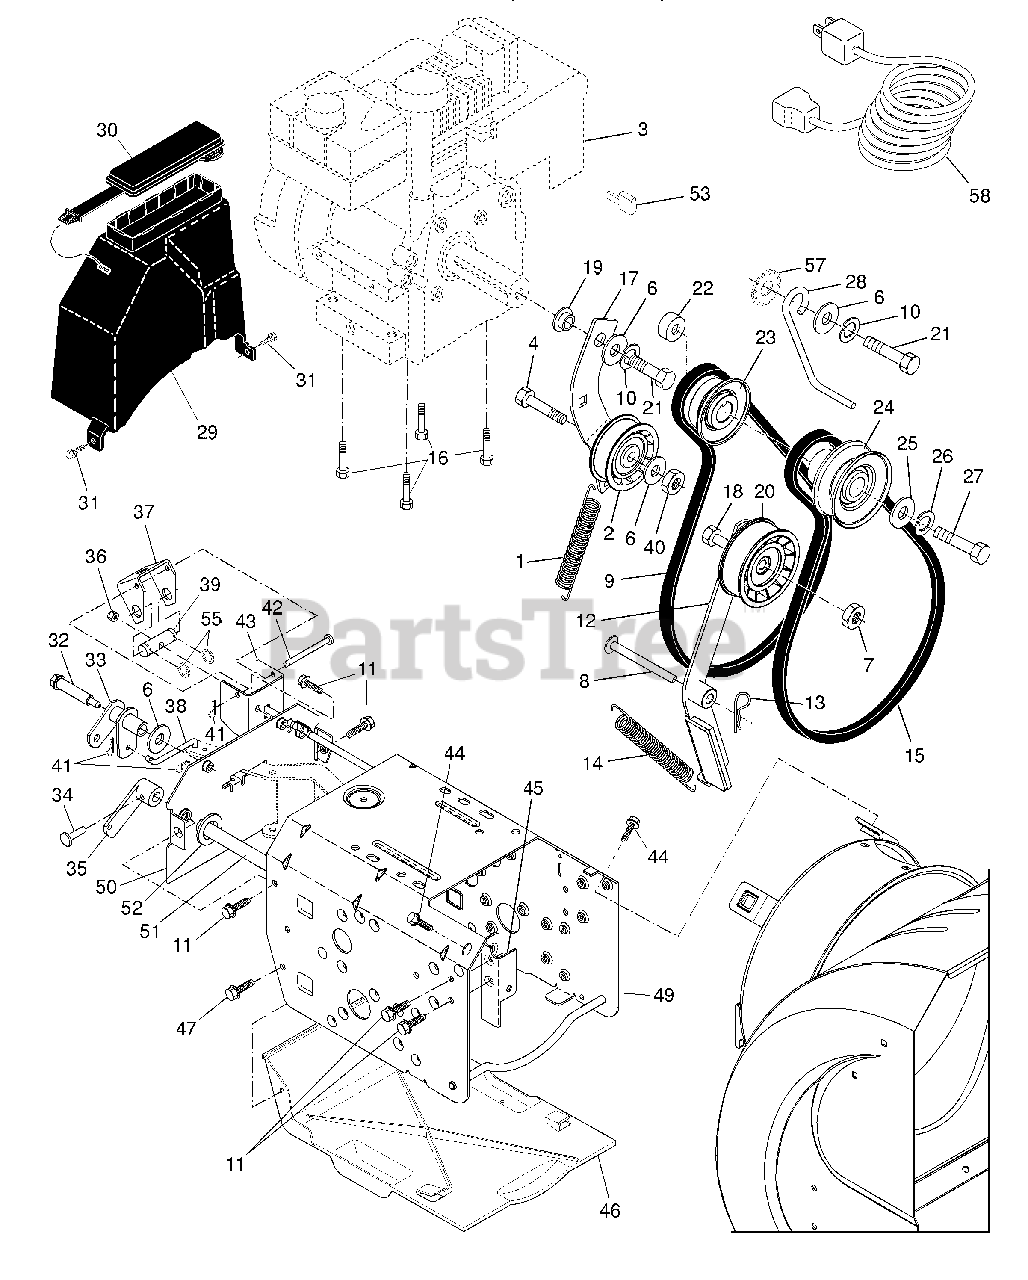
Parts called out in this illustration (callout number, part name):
1	Spring, Traction Idler
2	Pulley, Idler
4	Screw, Hex Head 5/16-18 x 1-1/4
6	Washer, Flat
7	Nut, Jam, Lock 5/16-18
8	Pin, Idler Pivot
9	V-Belt, Traction Drive
10	Washer, Lock 5/16
11	Screw, Hex Head 5/16-18 x 1/2
12	Impeller Arm / Pad Assembly
13	Retainer, Hairpin
14	Spring, Brake
15	V-Belt, Impeller Drive
16	Screw, Hex Head 3/8-16 x 1-1/4
17	Arm, Idler
18	Screw, Hex Head 5/16-18 x 1-1/2
19	Bushing, Idler Pivot
20	Pulley, Idler
21	Screw, Hex Head 5/16-18 x 1
22	Spacer, Engine Pulley
23	Pulley, Engine, Traction Drive
24	Pulley, Engine, Impeller Drive
25	Washer, Flat 3/8
26	Washer, Lock, Helical 3/8
27	Screw, Hex Head 3/8-24 x 1-3/8
28	Guide, Belt
29	Belt Cover Assembly
30	Cover, Toolbox
31	Screw, Hex Head 1/4-20 x 1/2
32	Bolt, Shoulder 5/16-18
33	Bellcrank Shifter
34	Clevis Pin
35	Arm, Auger Control
36	Nut, Lock 5/16-18
38	Link, Speed Control
39	Trunnion, Pivot Bracket
40	Locknut, Hex
41	Hairpin, Cotter 3/32 x 1/2
42	Pin, Bellcrank
43	Bracket, Bellcrank
44	Screw, Hex Head
45	Pivot Bracket, Impeller Idler Arm
46	Pan, Frame Bottom
47	Screw, Shoulder #10-24
49	Frame Assembly
50	Plate, Frame End
51	Shaft, Auger Control
52	Washer, Hardened
53	Key, Safety
55	Ring, Crescent
57	Washer, Lock, External Tooth 5/16
58	Power Cord
